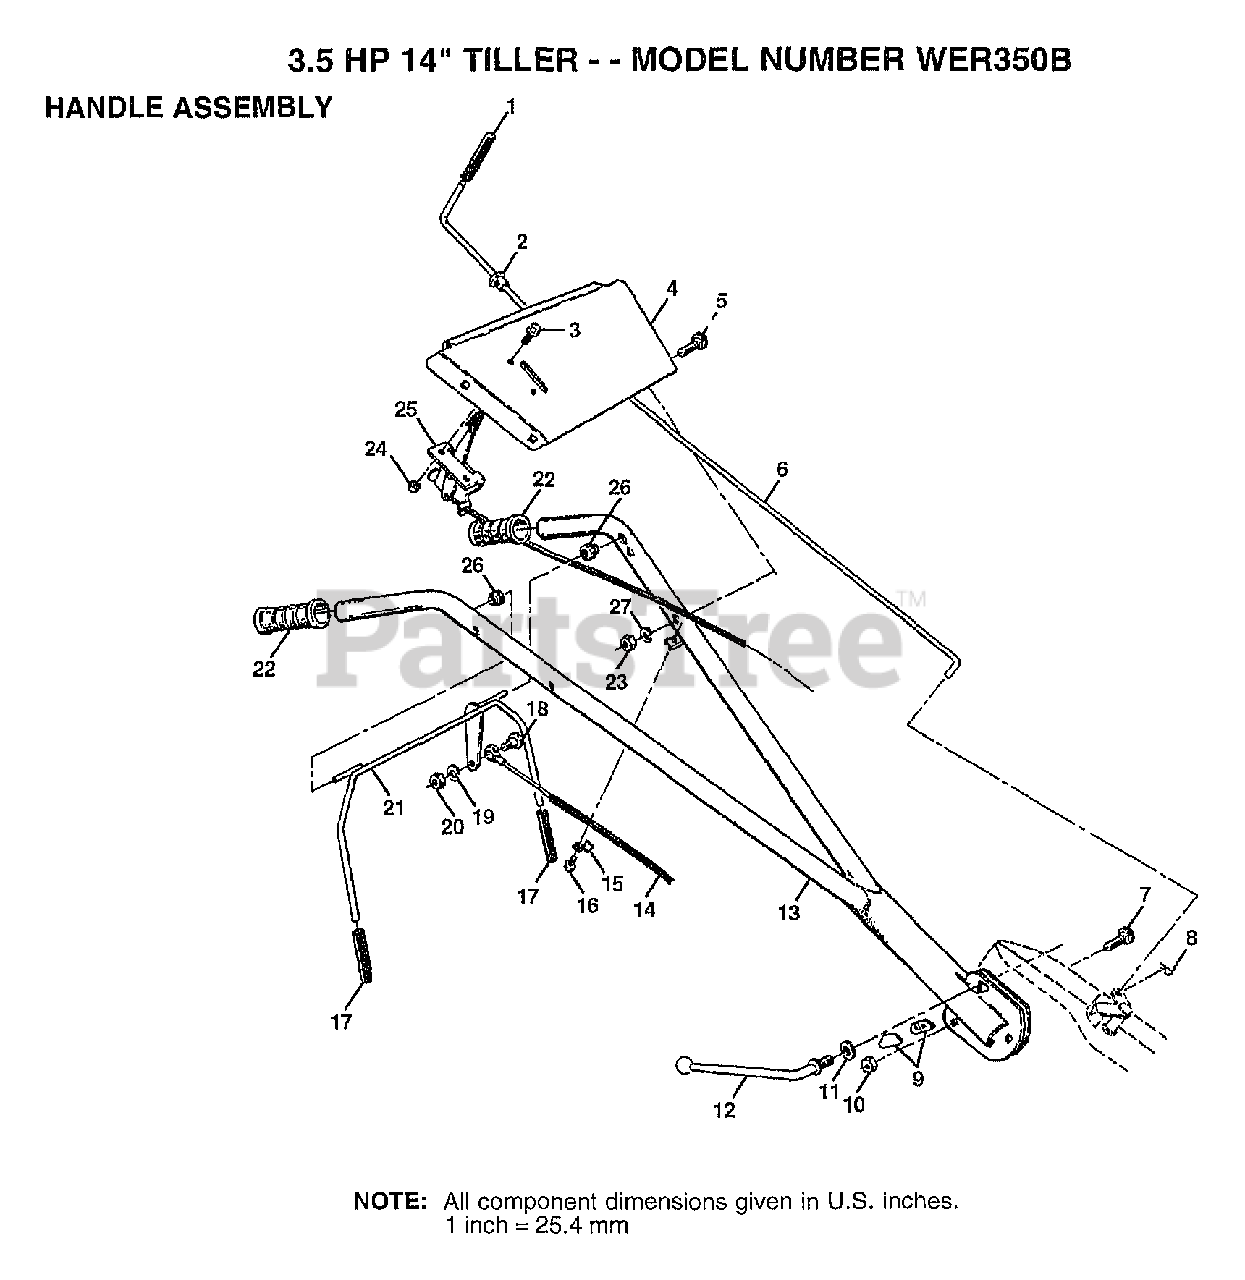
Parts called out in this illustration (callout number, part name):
1	GRIP TI
2	BUSHING
3	SCREW
5	BOLT CARRIAGE CRT
6	ROD SHIFT CRT
7	BOLT D
8	RETAINER M
9	LOCK CRT
10	LOCKNUT
11	WASHER CRT
12	LEVER LOCK CRT
14	CABLE.CLUTCH.CRT
15	CONDIUT CLIP T
17	GRIP BAR CRT
18	SHOULDER BOLT ST
19	LOCKWASHER
21	HANDLE BAR CRT
22	GRIP HDLE NUBBED
23	NUT
25	"CONT,THROTTLE"
27	LOCKWASHER
